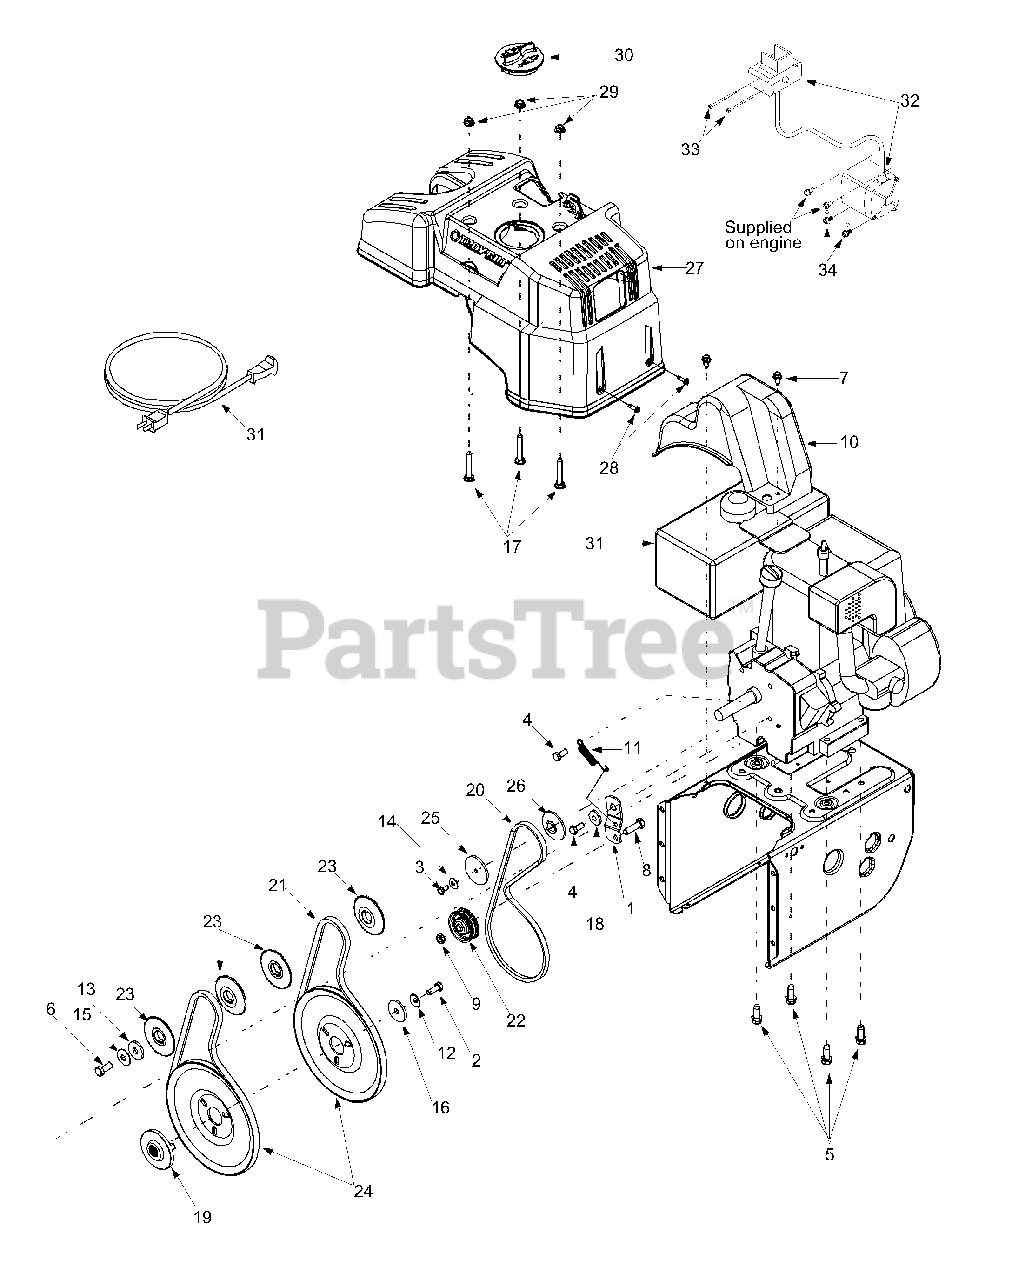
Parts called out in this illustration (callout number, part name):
3	Hex Screw 1/4-28 x .50"
4	Hex Screw 5/16-24 x .750"
5	TT Screw 3/8-16 x 1.0"
6	Hex Screw 3/8-24 x .875"
7	TT Screw 1/4-20 x .625"
8	Hex Screw 3/8-16 x 1.25"
10	Belt Cover
11	Extension Spring
12	Bell Washer
13	Flat Washer .406 x 1.25
14	Bell Washer .265 x .75 x .062
15	Bell Washer .390 x 1.13 x .062
16	Flat Washer .34 x 1.5 x .150
18	Shoulder Spacer
19	Pulley
20	V-Belt
21	Belt
22	Flat Idler Pulley
23	Pulley Half
24	Auger Pulley
25	Pulley Half
26	Pulley Half
27	Shroud
28	Hex Screw #10-16 x .75"
29	Flange Lock Nut 5/16-18
30	Spark Plug Access
31	Extension Cord
32	Electric Starter
33	Hex Screw #6-32 x 2.5
34	Hex Screw 1/4-20 x .500
